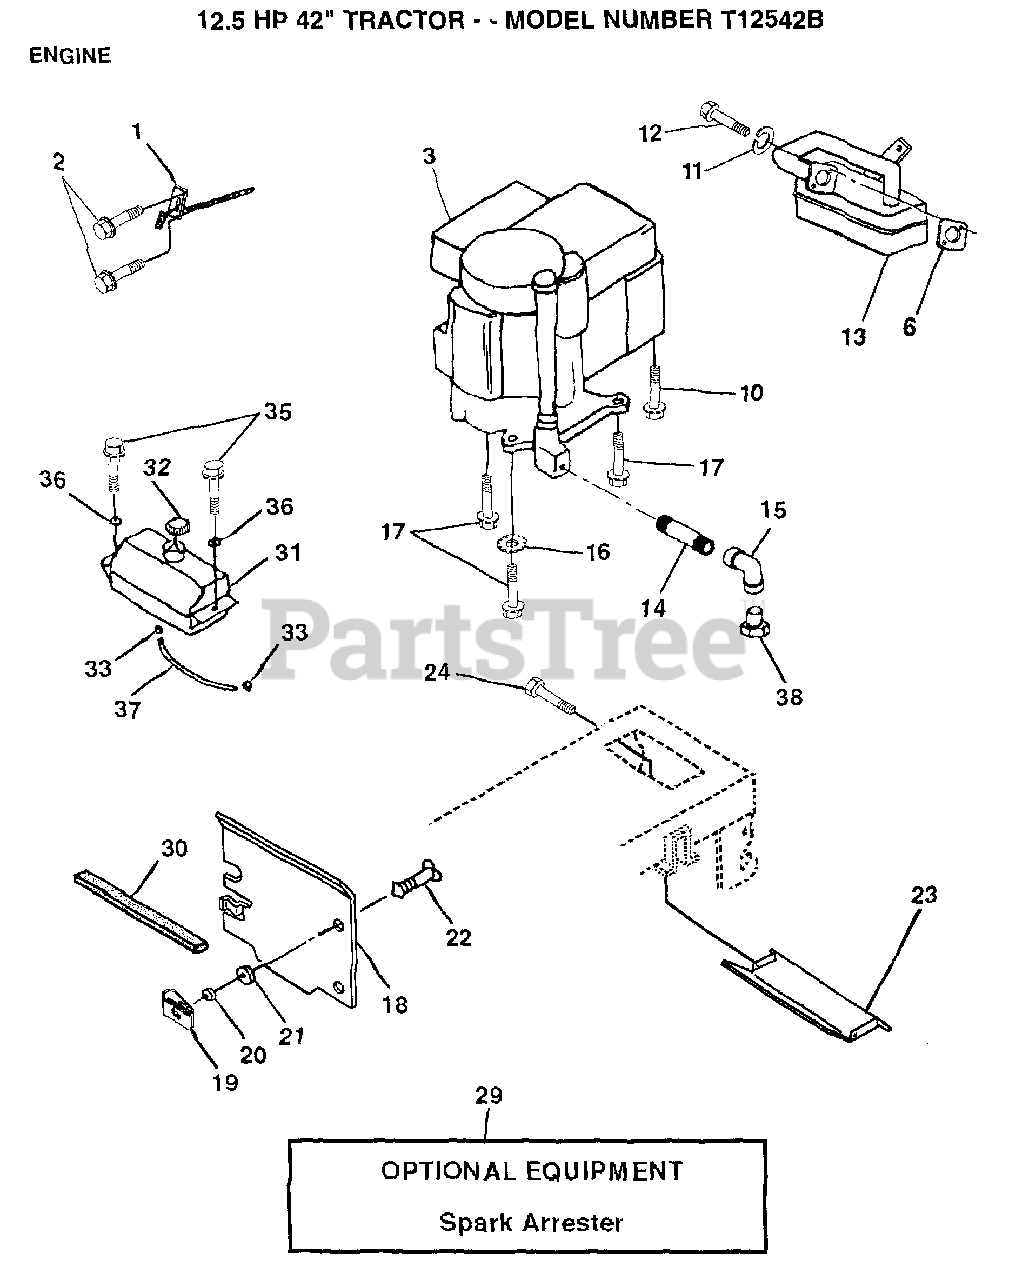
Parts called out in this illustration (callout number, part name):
1	CONTROL THROTTLE
2	SCREW LT
10	SCREW
11	LOCKWASHER
12	SCREW
13	MUFFLER
14	PIPE NIPPLE
15	ELBOW
16	LOCKWASHER
17	SCREW
18	SHIELD HEAT
19	RECEPTACLE LT
20	RETAINER LT
21	WASHER
22	STUD.1/4.TURN
23	HEAT SHIELD
24	SCREW
31	TANK.FUEL.LT.
32	CAP ASM FUEL
33	HOSE CLAMP
35	SCREW HEX CRT
36	WASHER
37	LINE FUEL
